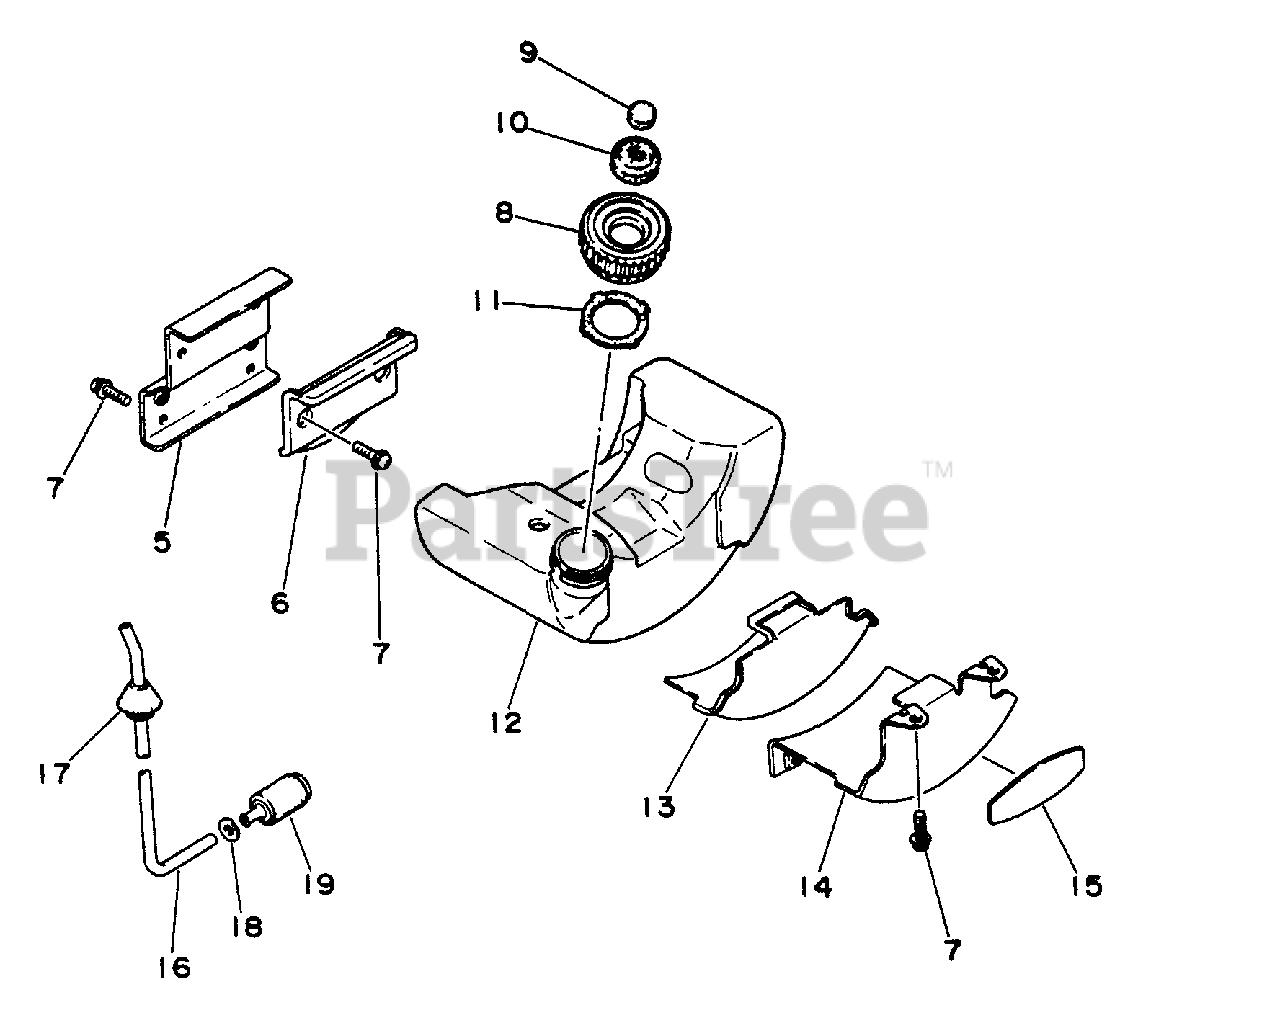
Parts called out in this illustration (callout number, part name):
5	BRACKET, FUEL TANK
6	CUSHION, FUEL TANK
7	SCREW 4×14
8	CAP ASSY
9	FILTER, CHECK VALVE
10	VENT ASSY
12	TANK, FUEL
14	BRACKET, FUEL TANK
15	LABEL - ECHO
18	WASHER 5.5×12×0.8
19	FILTER, FUEL
